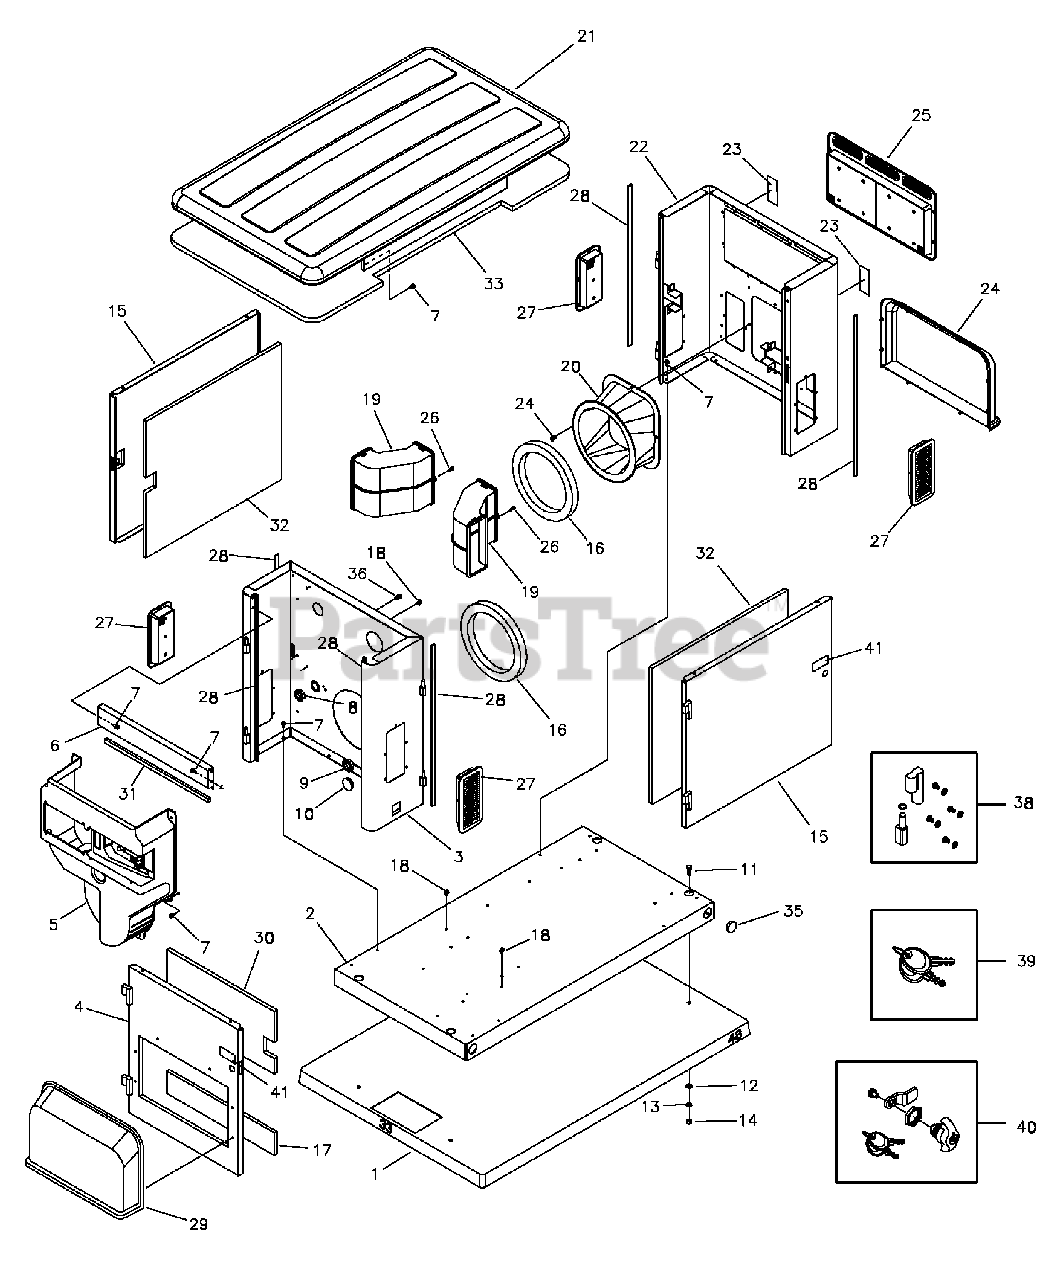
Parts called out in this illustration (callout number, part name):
1	PAD, Mounting w/ Holes
2	BASE, Mounting
3	ASSY, Bulkhead, Engine End
4	DOOR ASSEMBLY, Engine End
5	DUCT ASSEMBLY, Engine Air
6	SUPPORT RAIL ASSEMBLY
7	HHS, Trilobular, 1/4-20 x 1/2
8	BUSHING, Snap, 1-3/8"
9	BUSHING, Snap, 1-1/2"
10	PLUG, Dome, 1-1/2"
11	* CAPSCREW, Hex Head, 3/8-16 x 1
12	* WASHER, Flat, 3/8 - M10
13	* WASHER, Lock 3/8
14	* NUT, 3/8-16
16	SEAL, Foam, Engine Air
17	INSULATION, Engine Door, Bottom
18	MOUNT, Tie Wrap
19	DUCT, Rubber Alternator
20	ADAPTER, Alternator
21	ASSEMBLY, Roof/Siderails
22	BULKHEAD ASSEMBLY, Alternator End
23	DECAL, Hot Surface
24	COVER, Air Intake Alternator
25	VENT ASSEMBLY, Exhaust
27	VENT ASSEMBLY, Alternator
29	COVER, Air Intake Engine
30	INSULATION, Engine Door, Top
32	INSULATION, Front/Rear Door
33	INSULATION, Roof
38	KIT, Door, Hinge
41	DECAL, Manual/Hazard
